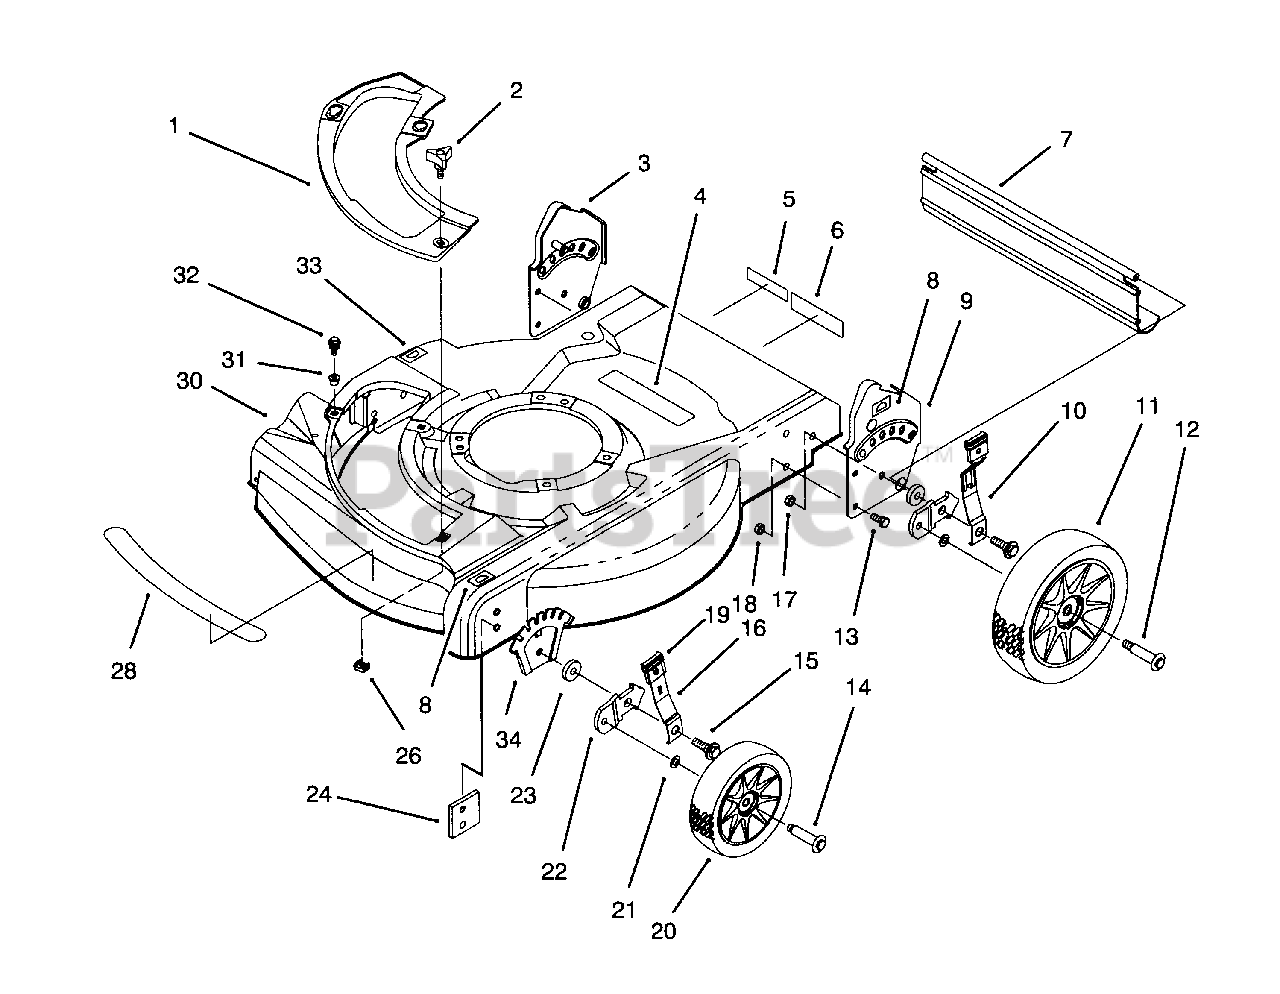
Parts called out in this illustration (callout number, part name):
1	Plate-Cover
2	Knob-Cover Plate
3	Handle Brkt. Ass'y-R.H.
4	Decal-Danger
5	Decal-French Regulation
6	Decal-DIN
7	Shield-Trailing
8	Decal-H.O.C.
9	Handle Brkt. Ass'y-L.H.
10	Spring Arm Ass'y
11	Wheel & Tire Assembly
12	Bolt-Shoulder
13	Screw-Hex Hd. Cap
14	Bolt-Shoulder
15	Bolt-Shoulder Height Adj.
16	Spring Arm Ass'y
17	Nut-Lock
18	Nut-Lock
19	Knob-Height Adjust
20	Wheel & Tire Assembly
22	Bracket-Wheel Height Adj.
24	Plate-Baffle
26	Nut-Cage
28	Decal-Deck 345VP
31	Grommet-Plastic
32	Screw-Sems Thr'd Form
33	Decal-H.O.C.
34	Plate-Height Adjust
